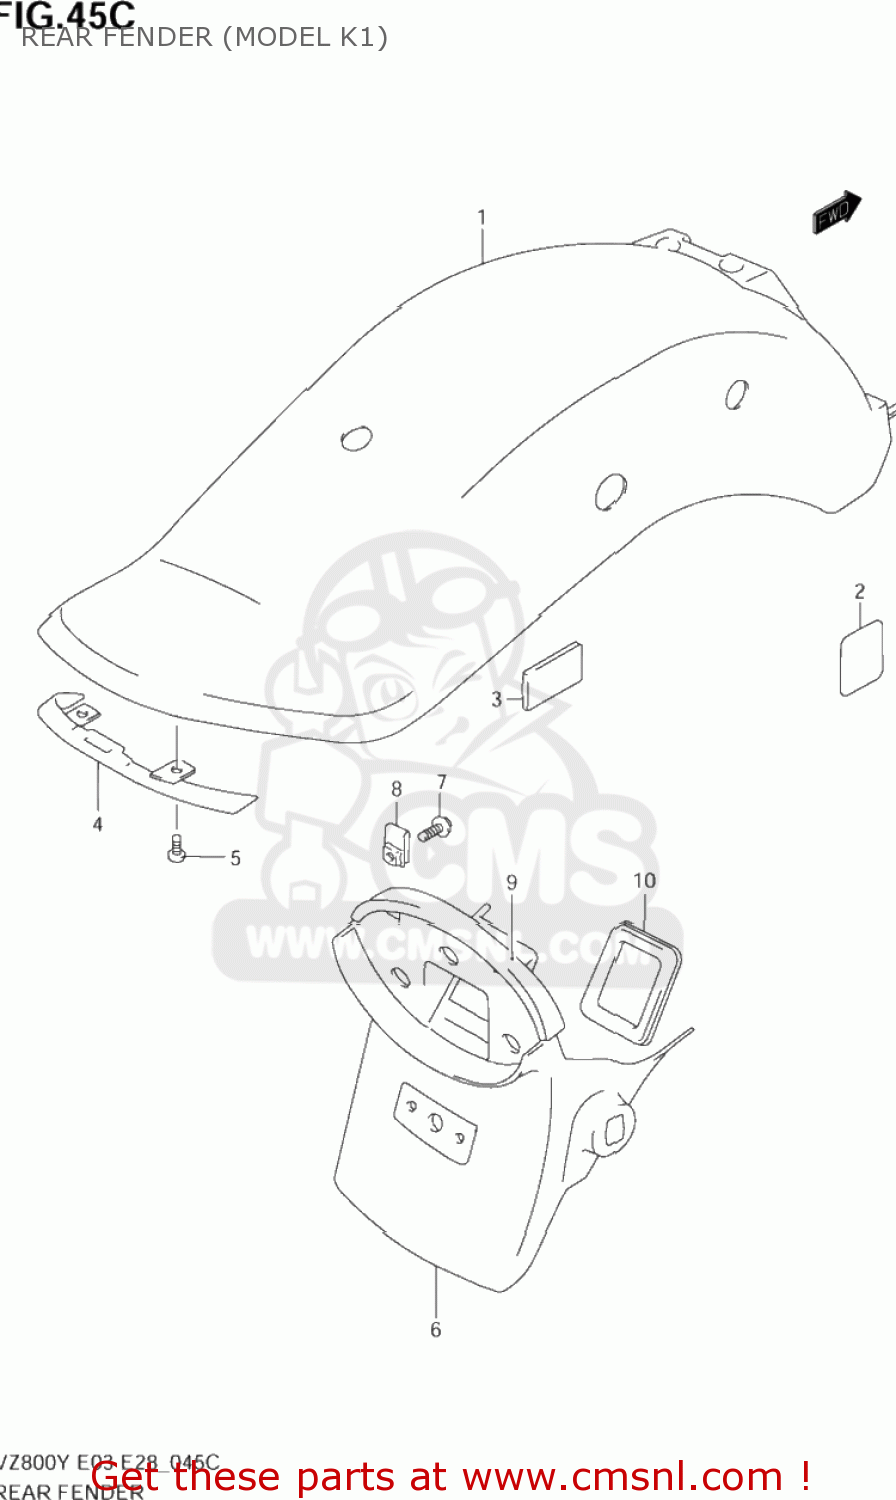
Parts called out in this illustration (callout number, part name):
1	FENDER,RR
2	PAD
3	CUSHION
4	COVER,RR FENDER RR
5	SCREW
6	EXTENSION,RR FENDER
7	SCREW
8	PLATE,FRAME COVER
9	CUSHION,RR FENDER EXTENSION
10	CAP,RR FENDER EXTENSION
